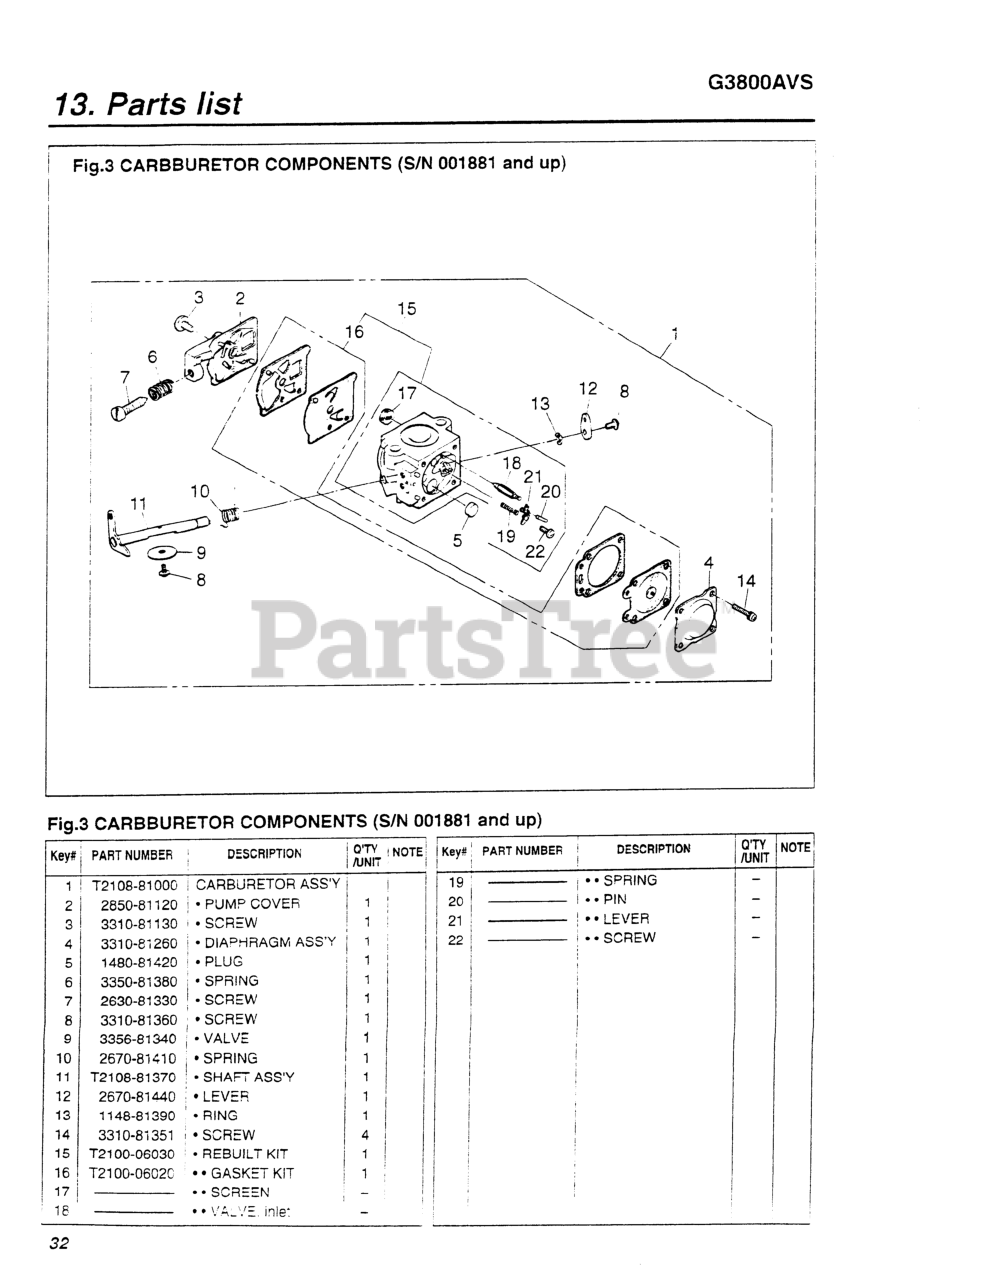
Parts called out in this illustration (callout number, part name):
1	CARBURETOR ASSEMBLY
2	COVER, PUMP
4	DIAPHRAGM (USE 4810-81260)
5	PLUG, WELSH
6	SPRING, IDLE
9	VALVE, THROTTLE
10	SPRING, RETURN
11	SHAFT ASSEMBLY, THROTTLE
12	VALVE, THROTTLE
14	SCREW ASSEMBLY
15	REBUILD KIT
16	KIT, GASKET (G3800AVS)
17	SCREEN
18	VALVE, INLET
20	PIN
21	LEVER
22	SCREW
